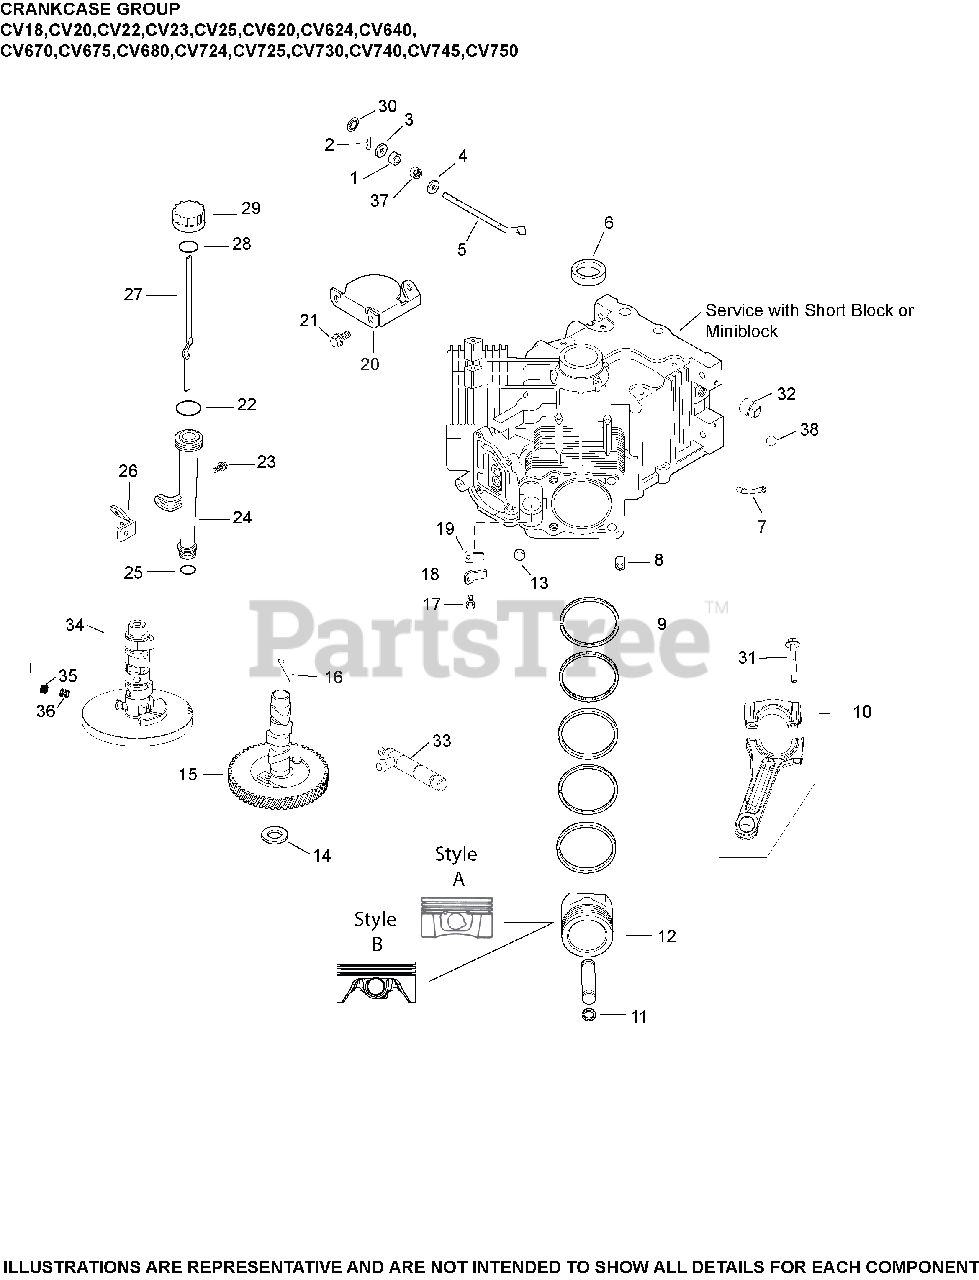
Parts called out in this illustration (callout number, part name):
1	SEAL, GOVERNOR CROSS SHAFT
3	WASHER, FLAT 9 MM
4	WASHER, FLAT 11/32"
5	SHAFT, GOVERNOR CROSS
6	SEAL, OIL (HELIX LIP)
8	PIN, LOCATING
9	DISC USE PISTON ASSY PER SPEC-RING SET(STD)STYLE A-1.5mm Tp RING THICK - Discontinued
9	RING SET(.08)STYLE A-1.5mm Tp RING THICK
9	RING SET(.25)STYLE A-1.5mm Tp RING THICK
9	RING SET(.50)STYLE A-1.5mm Tp RING THICK
9	RING SET(STD)STYLE B-1.2mm Tp RING THICK
9	RING SET(.08)STYLE B-1.2mm Tp RING THICK
9	RING SET(.25)STYLE B-1.2mm Tp RING THICK
9	RING SET(.50)STYLE B-1.2mm Tp RING THICK
10	ROD, ASSY CONNECTING (STD)-(#2406730S)
10	ROD ASSY, CONNECTING U/S (.010”) (.25 mm) -USE 24 067 31-S
11	RETAINER, PISTON PIN
12	PISTON W/RINGS (STYLE A) (STD) - RING SET 24 108 14-S USE 25 874 13-S
12	PISTON W/RINGS (STYLE A)(0.08) - RING SET 24 108 15-S USE 25 874 07-S
12	PISTON W/RINGS (STYLE A)(0.25)(#2587408S) - RING SET 24 108 16-S
12	PISTON W/RINGS (STYLE A)(.50) - (#2587409S) - RING SET 24 108 17-S
12	PISTON W/RINGS (STYLE B)(STD) - RING SET 25 108 01-S
12	PISTON W/RINGS (STYLE B)( 0.08) - RING SET 25 108 02-S
12	PISTON W/RINGS (STYLE B)(0.25) - RING SET 25 108 03-S
13	PLUG, CUP
15	KIT, CAMSHAFT
17	SCREW, FLG THD FRM M5X.8X10
18	RETAINER, BREATHER REED
19	REED, BREATHER
22	O-RING, DIPSTICK
24	TUBE ASSEMBLY
25	O-RING, LOWER OIL FILL TUBE
26	BRACKET, OIL FILL TUBE USE 24 126 243-S
27	DIPSTICK, ASSY
28	O-RING, DIPSTICK
29	KIT, OIL FILL CAP (BLACK)
30	RETAINER, RING
31	KIT, ROD BOLTS
1242207-S	SHIM, CAMSHAFT (WHITE .028")
